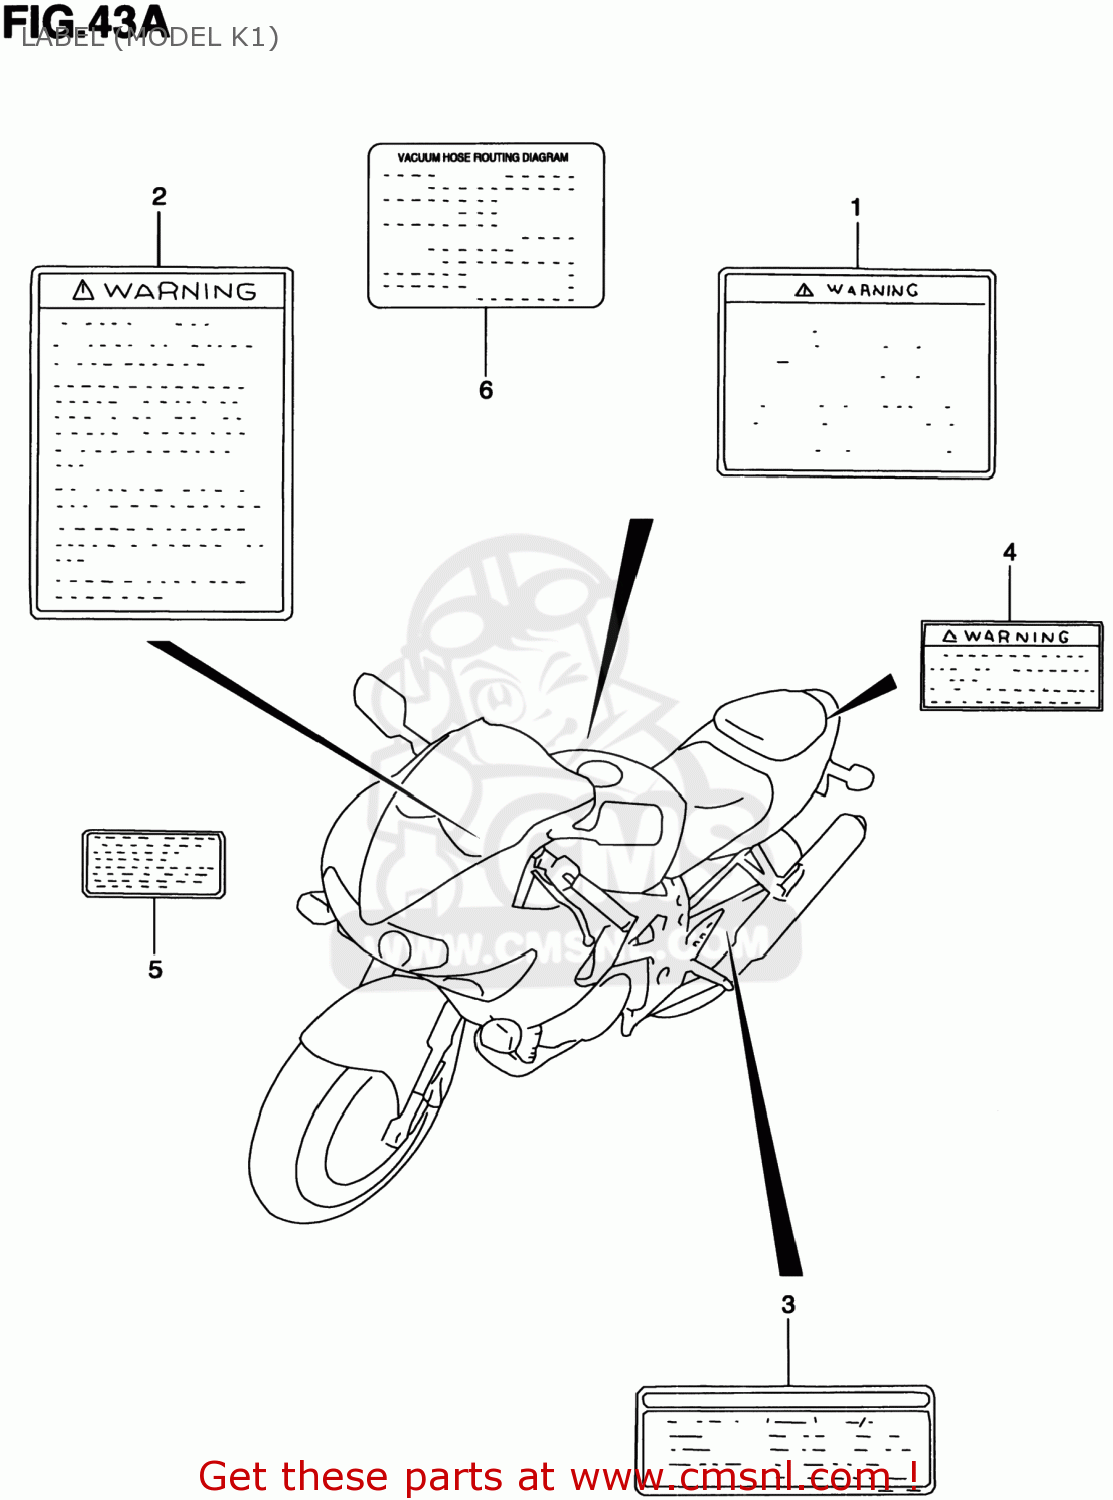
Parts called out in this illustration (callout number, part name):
1	LABEL,GENERAL WARNING
2	LABEL,WARNING SCREEN
3	LABEL,TIRE INFORMATION
4	LABEL (MANUAL NOTICE)
5	LABEL,WARNING STEERING
6	LABEL (VACUUM HOSE ROUTING)
7	MANUAL,OWNER'S TL1000SK1
